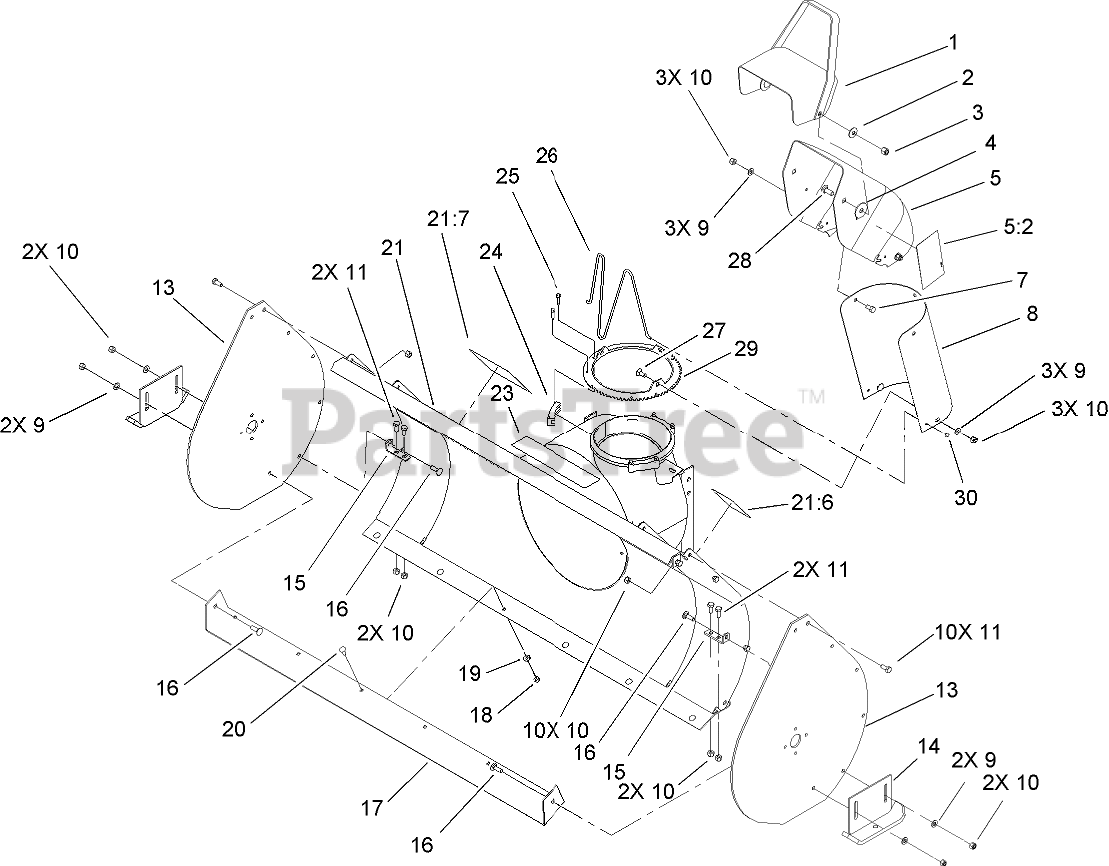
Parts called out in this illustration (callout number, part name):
1	DEFLECTOR
2	WASHER-BELLEVILLE
3	NUT-LOCK, NI
4	WASHER-RUBBER
5	CHUTE
5:2	DECAL-DANGER (only on: 38078)
7	SCREW-HH
8	EXTENDER-CHUTE, UPPER
9	WASHER-PLAIN
10	NUT-LOCK, NI
11	SCREW-HH
13	PLATE-SIDE
14	SUPPORT-SKID
15	BRACKET-SUPPORT, BLADE
16	BOLT-CARR
17	BLADE-SCRAPER
18	NUT-LOCK, NI
19	WASHER-FLAT
20	SCREW-CARR
21	AUGER HSG/DECAL ASM
21:6	DECAL-DANGER
21:7	DECAL-WARNING
23	DECAL-WORKHORSE
24	RETAINER-CHUTE
25	SCREW-SPECIAL
26	WIRE-CHUTE
27	BOLT-CARR
28	BOLT-CARR
29	RING-SWIVEL, CHUTE
30	NUT-PUSH
